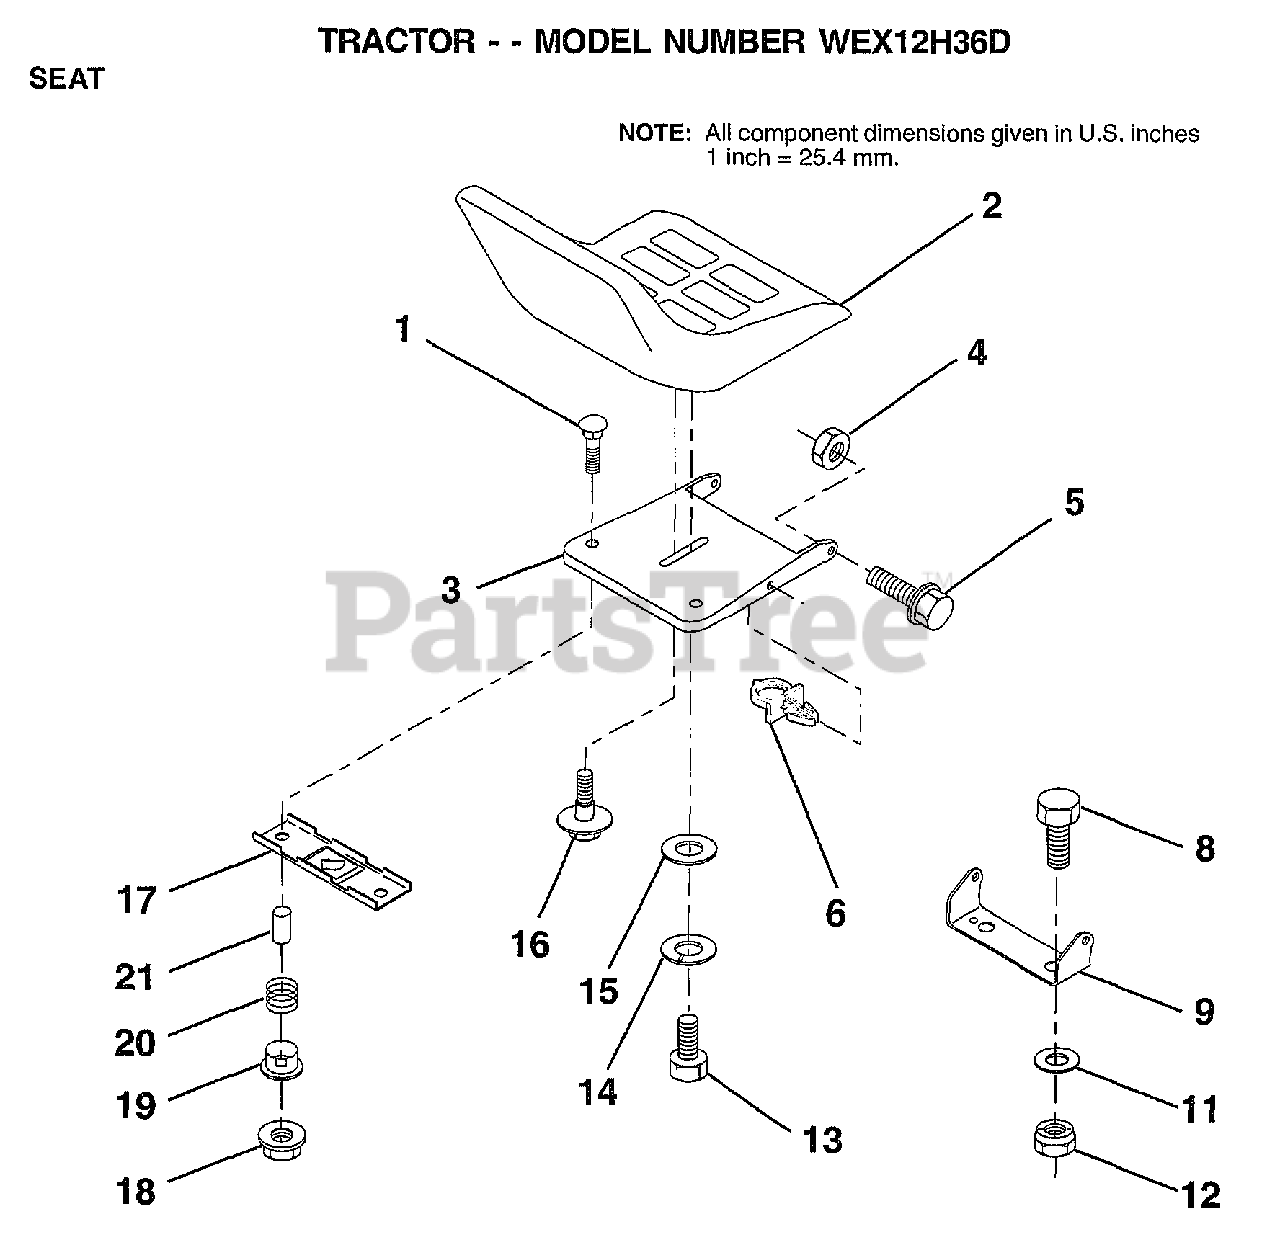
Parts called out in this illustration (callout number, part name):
1	BOLT-RD HD SQ NK
3	PAN-SEAT
4	NUT
5	BOLT
6	CLIP.PUSH-IN.HING
8	BOLT
9	BRACKET PVT SEAT
11	WASHER
12	NUT
13	BOLT
14	LOCKWASHER
15	WASHER
16	"BOLT,SHOULDER"
17	BRKT SWITCH
19	BUSHING
20	SPRING
21	SPLIT SPACER
